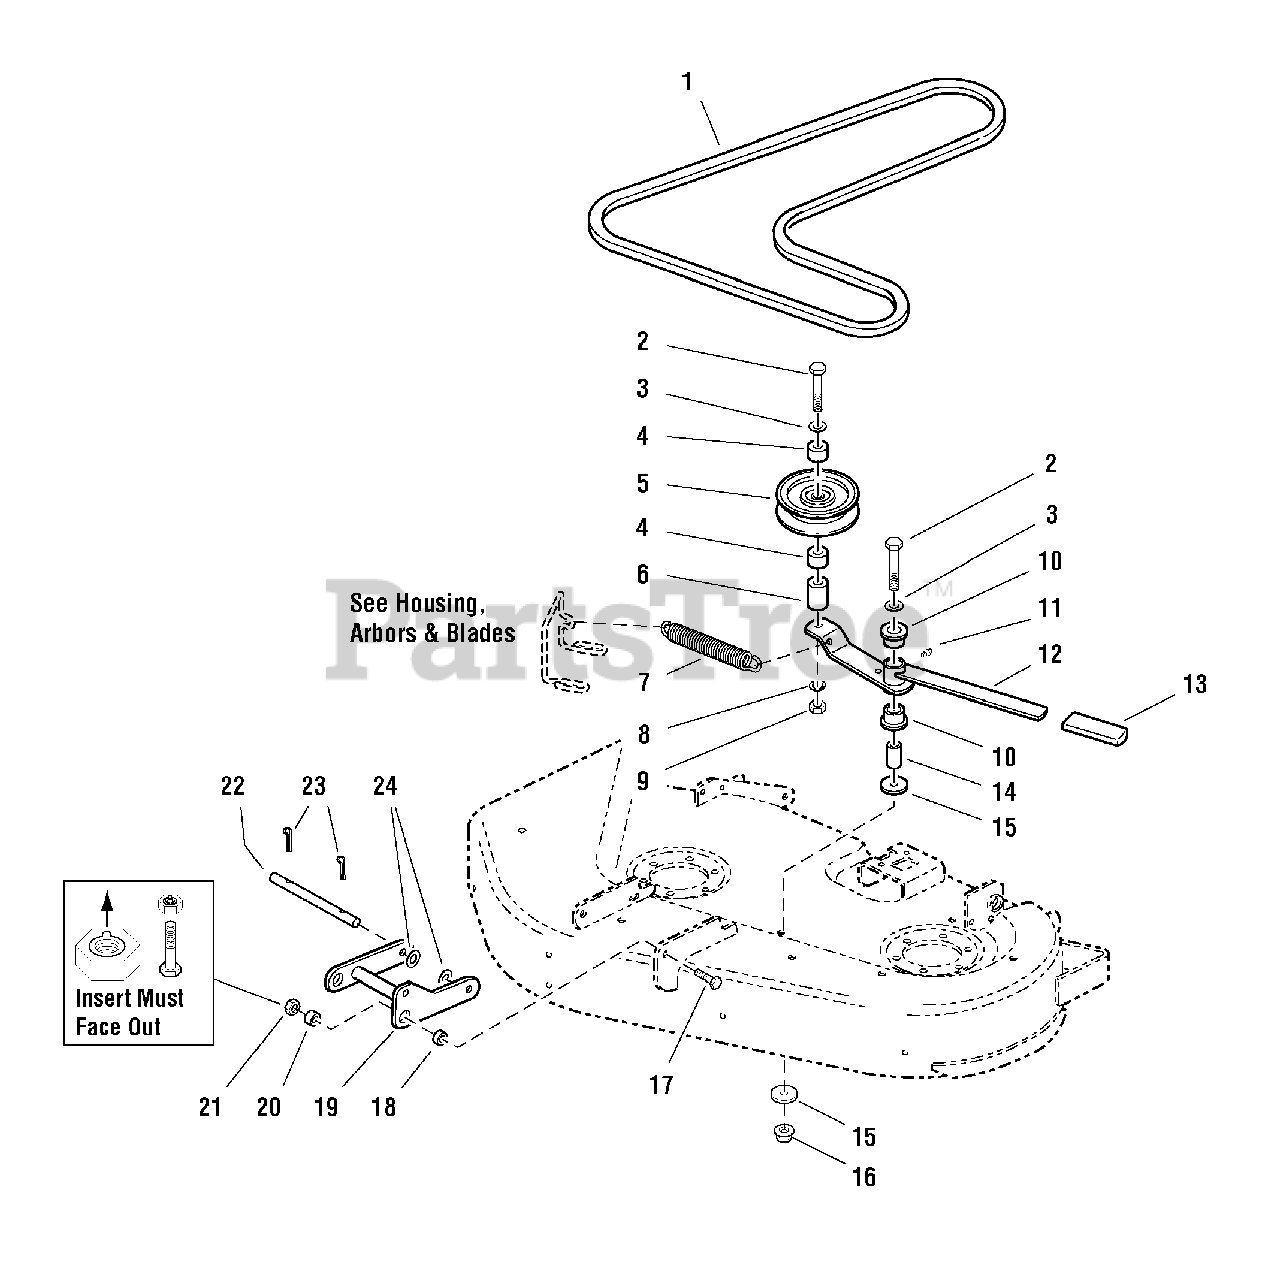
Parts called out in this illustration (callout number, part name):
2	CAPSCREW, Hex Head, 3/8-16 x 2-3/4
3	WASHER, 3/8
5	PULLEY, Idler
7	SPRING, Extension
8	LOCKWASHER, 3/8
9	NUT, Hex, 3/8-16
11	FITTING, Lube
12	LEVER & ARM ASSEMBLY, Complete (Includes Ref. No. 10 & 11)
13	GRIP
15	WASHER, 3/8
16	NUT, Hex Serrated Flange, 3/8-16
17	CAPSCREW, Hex Head, 3/8-16 x 1-1/2
21	NUT, Hex Flange, 3/8-16
23	PIN, Cotter
24	WASHER, 1/2
